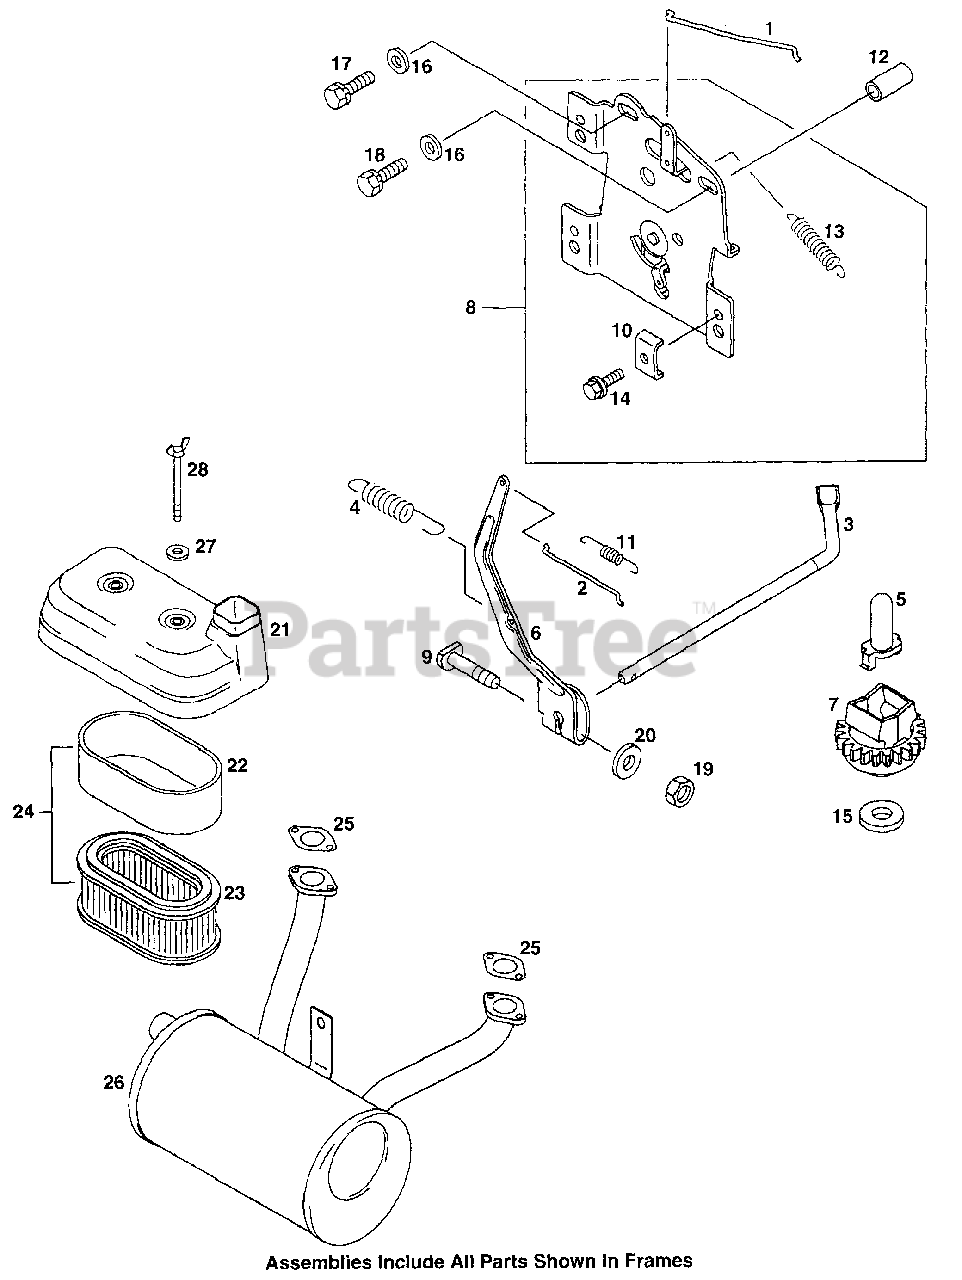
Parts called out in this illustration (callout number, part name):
4	Governor Spring
7	Governor Assembly
8	Control Panel
12	Collar, 6.8 x 10 x 20.5
14	Bolt, .5 x 18
17	Bolt-Upset-WS
18	Bolt-Upset-WS
19	Hex Nut
20	Plain Washer
21	Air Filter Case
22	Air Filter Precleaner
23	Air Filter Element
24	Air Filter Assembly
25	Muffler Gasket
26	Complete Muffler
